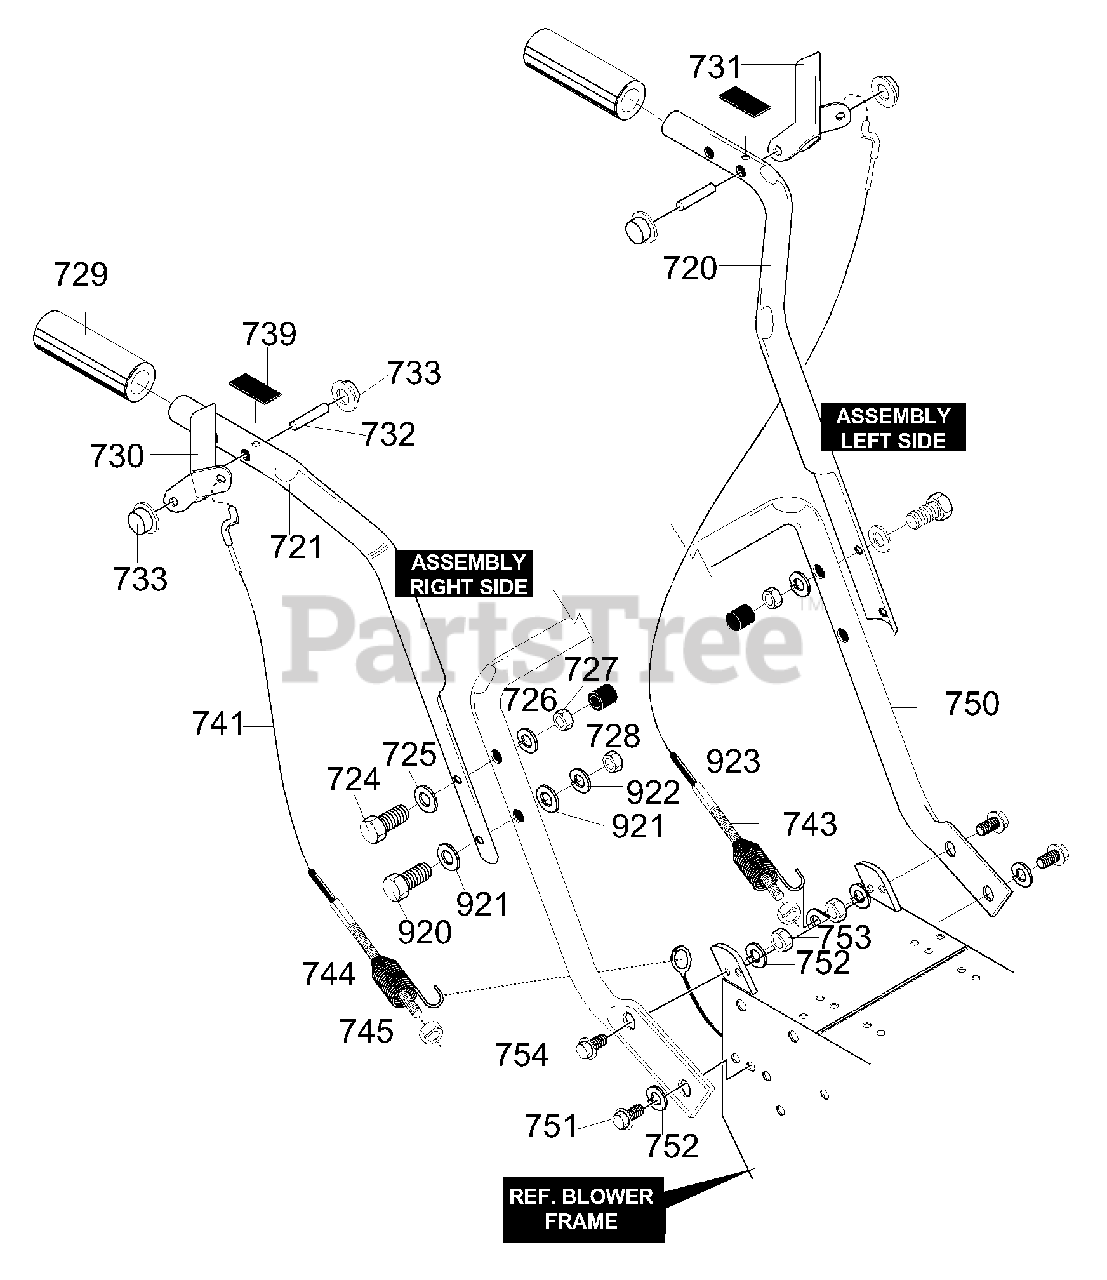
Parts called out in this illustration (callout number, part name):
720	UPPER HANDLE LH
721	UPPER HANDLE RH
724	SCREW, 3/8-16X3.00
725	FLATWASHER .406X.81X.065
726	WASHER, RGSPTLK .393X.68X.10
727	NUT, 3/8-16 REGHEXTRLK
728	STOP, PLASTIC .375
729	GRIP, HANDLE
730	HANDLE, CLUTCH RH
731	HANDLE, CLUTCH LH
732	PIN, PIVOT
738	PUSH ON CAP
739	BUMPER, RECT
741	CABLE, CLUTCH
743	SPRING, TENSION
744	SPRING, AUGER CLUTCH
745	NUT, 1/4-20 REGHEXCTRLK
750	HANDLE, LOWER
751	SCREW, 5/16-18X.75
752	WASHER, HVSPTLK .328X.60X.09
753	NUT 5/16-18 REGHEX
754	SCREW, 5/16-18X.75 WAHHTAP
920	SCREW, 3/8-16X2.00
921	FLATWASHER .406X.81X.065
922	WASHER RGSPTLK .393X.60X.10
923	NUT, 3/8-16 REGHEXCTRLK
